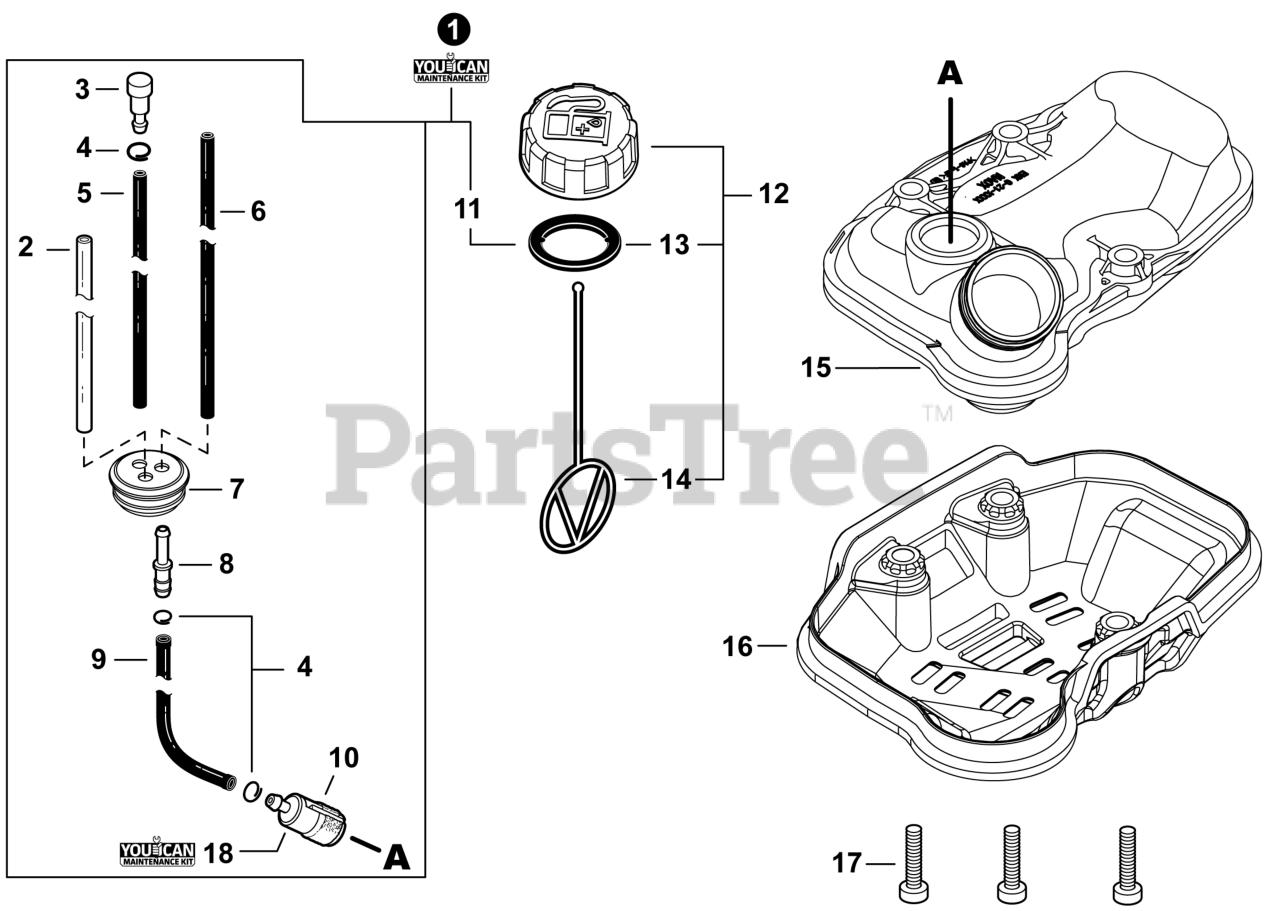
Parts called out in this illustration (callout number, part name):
1	FUEL SYSTEM KIT - YOUCANT
2	PIPE, FUEL 3x6x85 YELLOW
3	VENT ASSY
5	PIPE, FUEL 3x5x90 BLACK
6	PIPE, FUEL 3x5.5x78 BLACK
7	GROMMET, FUEL
8	CONNECTOR, PIPE 5x3.5
9	PIPE, FUEL 3x5x105 BLACK
10	FILTER, FUEL
11	GASKET, FUEL CAP
12	CAP ASSY, FUEL
13	GASKET, FUEL CAP
14	CONNECTOR, CAP L= 123
15	TANK ASSY, FUEL
16	GUARD, FUEL TANK
17	BOLT, TORX 5x25
18	TUNE-UP KIT - YOUCANT
